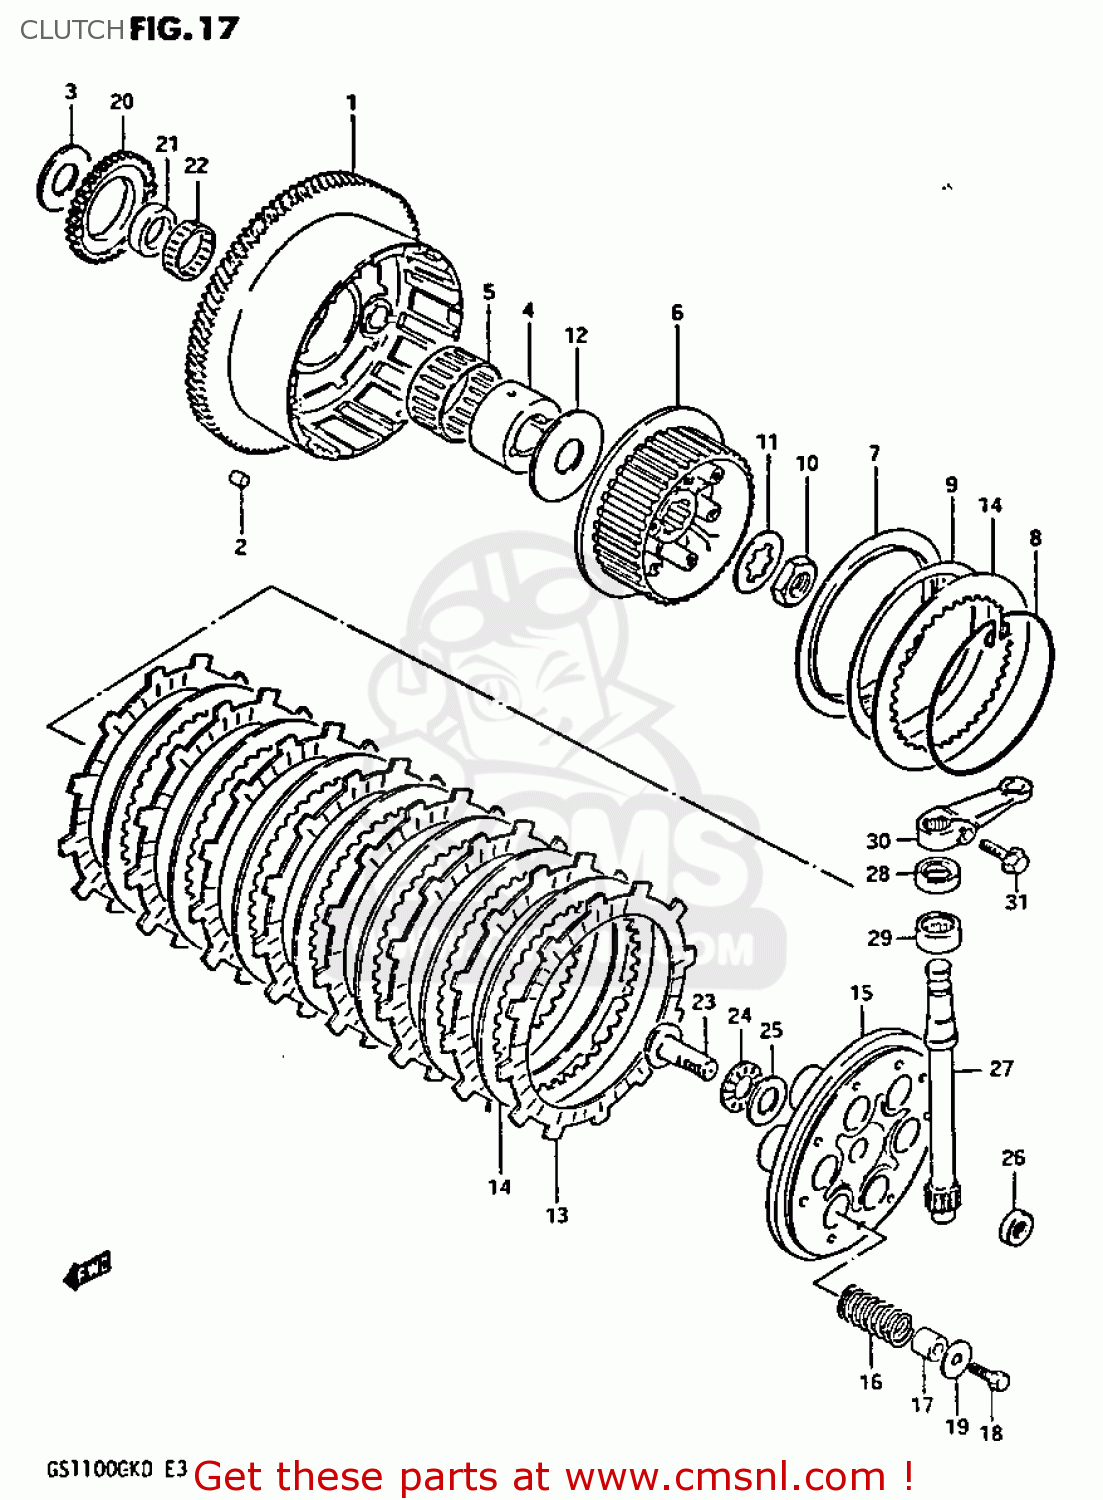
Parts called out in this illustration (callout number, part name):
1	GEAR ASSY,PRI DRIVEN
2	CUSHION,PRIMARY DRIVEN GEAR
3	WASHER(25X50X2.5)
4	SPACER
5	BEARING(51X56X28)
6	HUB,CLUTCH SLEEVE
7	SEAT,WAVE WASHER
8	RING,STOPPER
9	WASHER
10	NUT
11	WASHER,LOCK
12	WASHER(25X66X3.5)
13	PLATE,CLUTCH DRIVE (MCA)
14	PLATE,CLUTCH DRIVEN (NAS)
15	PLATE,CLUTCH PRESSURE
16	SPRING
17	SPACER(6.2X12X14)
18	BOLT
19	WASHER(6.5X20X1.6)
20	GEAR,ENG OIL PUMP DRIVE(NT:34)
21	SPACER,OIL PUMP DRIVE GEAR
22	BEARING(36X40X10)
23	RACK,CLUTCH RELEASE
24	BEARING(15X28X2)
25	WASHER(15.5X28X1)
26	SEAL,OIL(10X16X5)
27	PINION,CLUTCH RELEASE
28	OIL SEAL
29	BEARING(15X22X12)
30	ARM,CLUTCH RELEASE
31	BOLT 6X20
